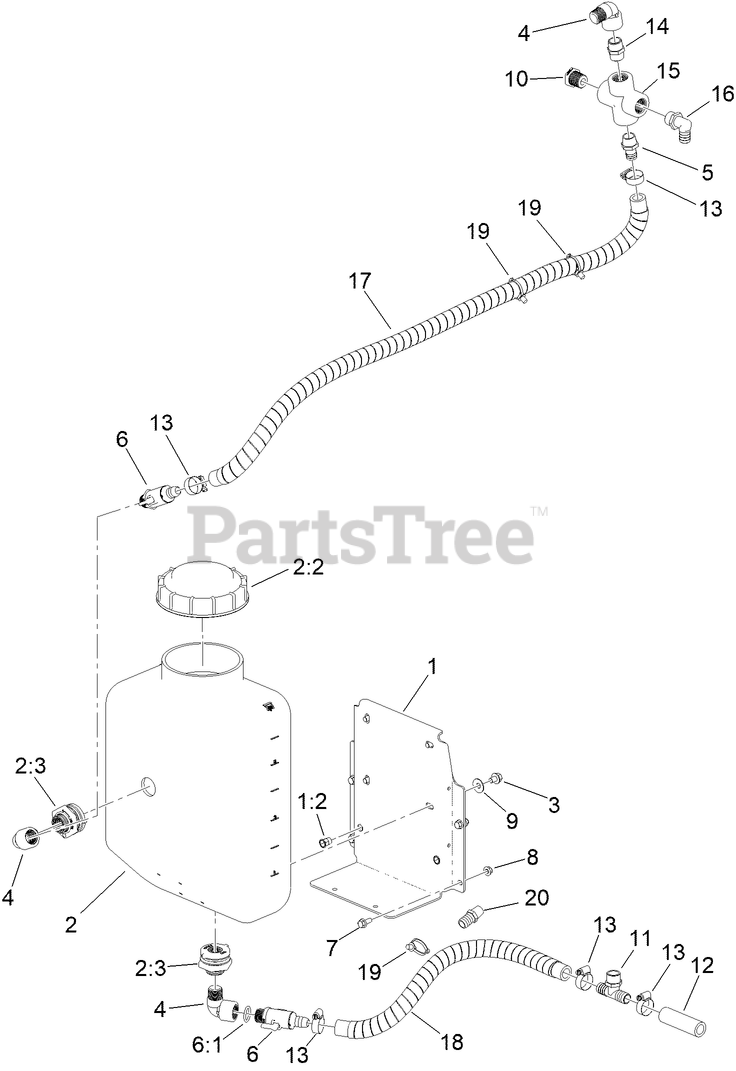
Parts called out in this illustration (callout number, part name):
1	BRACKET ASM, 7 GAL ISO TANK
1:2	NUT-CLINCH
2	7 GAL AUX/ISO TANK ASM
2:2	CAP-TANK, SPRAY
2:3	FITTING-BULKHEAD
3	SCREW-HHF
4	ELBOW-90 DEG
5	HOSEBARB
6:1	O-RING, -213
7	SCREW-HHF
8	NUT-HEX FLANGE
9	WASHER-SPRING
10	FITTING-PLUG
11	FITTING-TEE
12	HOSE-SPRAY
13	CLAMP-HOSE
14	FITTING-NIPPLE
15	FITTING-CROSS
16	FITTING-ELBOW, 90
17	HOSE-SPRAY, WRAPPED
18	HOSE-SPRAY, WRAPPED
19	CLIP-TIE
20	FITING-STRAIGHT
